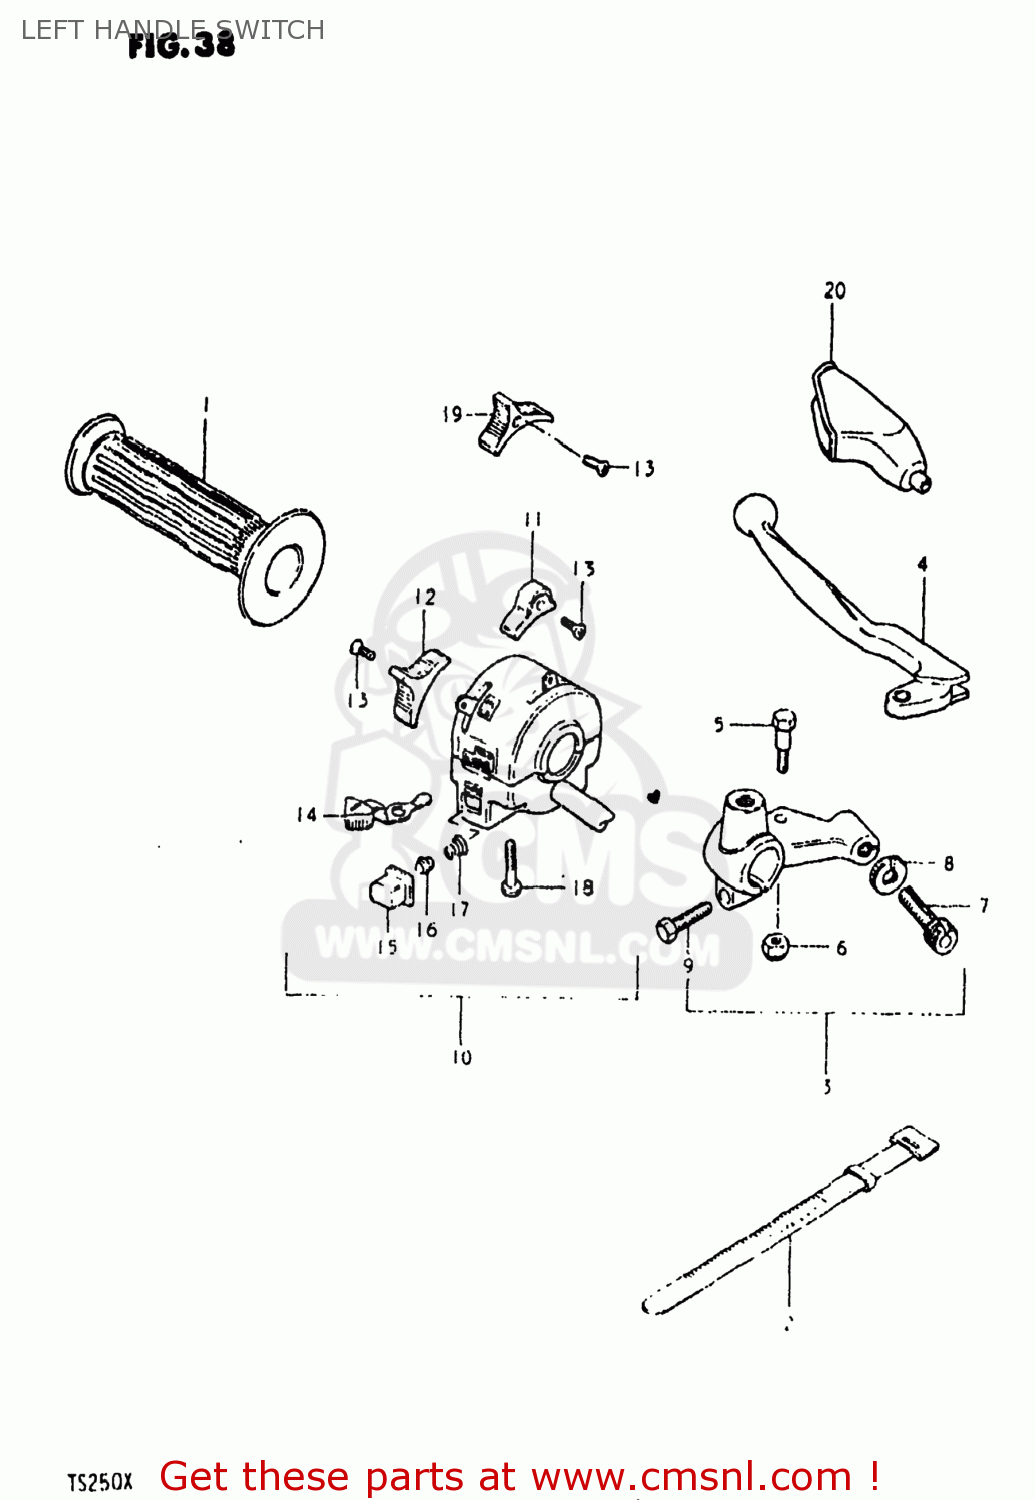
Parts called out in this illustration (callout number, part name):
1	GRIP,L
2	CLAMP(L:120)
3	LEVER ASSY,CLUTCH
4	LEVER,CLUTCH
5	BOLT,LEVER
6	NUT 6MM
7	ADJUSTER,CABLE
8	NUT,CABLE ADJUSTER
9	BOLT
10	SWITCH ASSEMBLY,HANDLE,LEFT
11	KNOB,STOP
12	KNOB,DIMMER SWITCH
13	SCREW
14	KNOB,TURNSIGNAL
15	BUTTON,HORN
16	CONTACT
17	SPRING
18	SCREW
19	KNOB,LIGHTING SWITCH
20	COVER,CLUTCH LEVER
